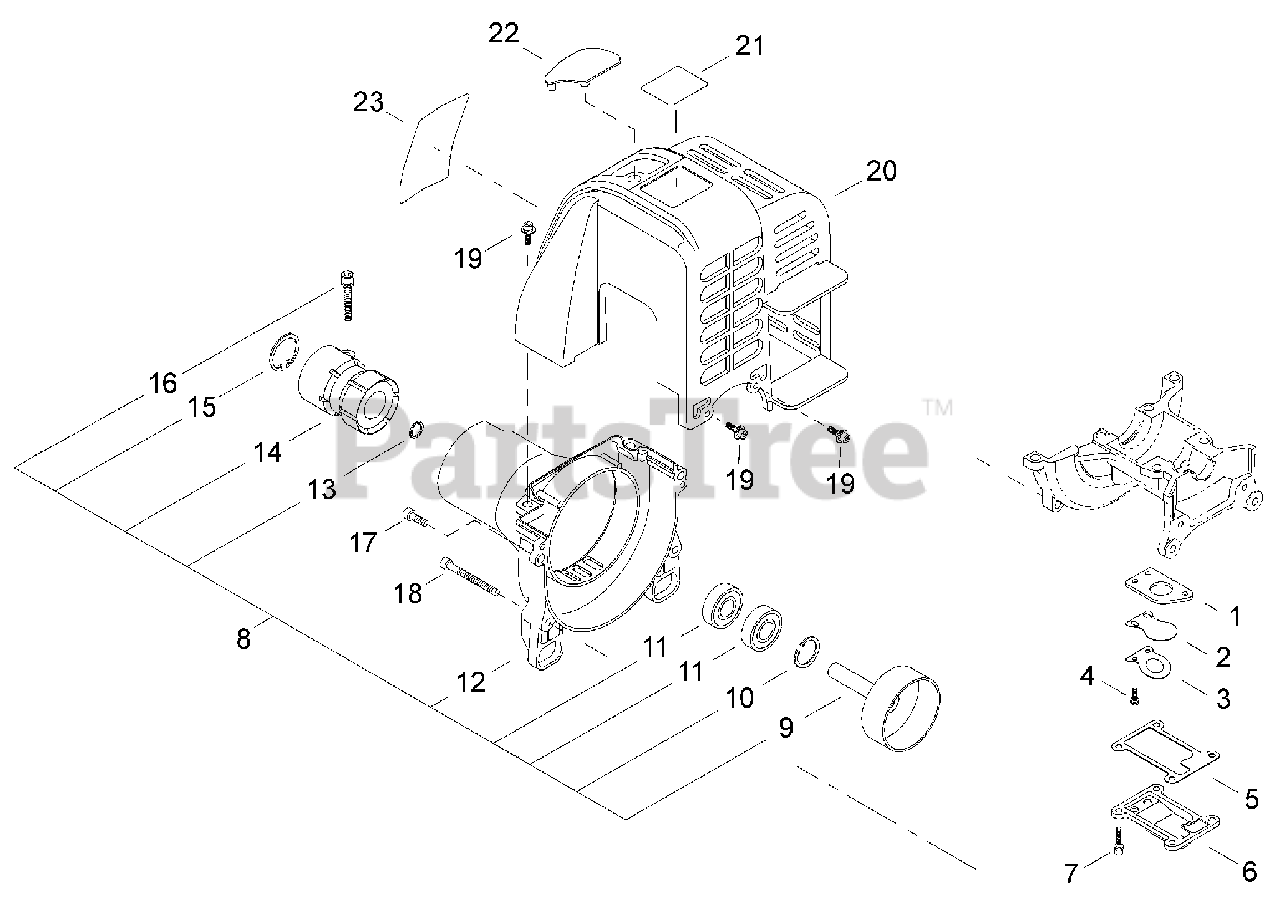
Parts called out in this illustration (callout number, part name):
1	PLATE, REED BACKING
2	VALVE, REED
3	STOP, REED VALVE
4	SCREW - 3X10
5	GASKET, REED VALVE
6	COVER, REED VALVE
7	SCREW - 4X12
8	FAN CASE ASSY
9	DRUM, CLUTCH
10	RING, RETAINING - 26
11	BEARING, BALL - 6000
12	CASE, FAN
13	RING, RETAINING
14	CUSHION
15	RING, RETAINING - 40
16	SCREW - 5X22
17	SCREW - 5X16
18	SCREW - 5X45
19	SCREW - 4X16
20	COVER, ENGINE
21	LABEL - MODEL HT4000
22	COVER, SPARK PLUG
23	LABEL - E4
